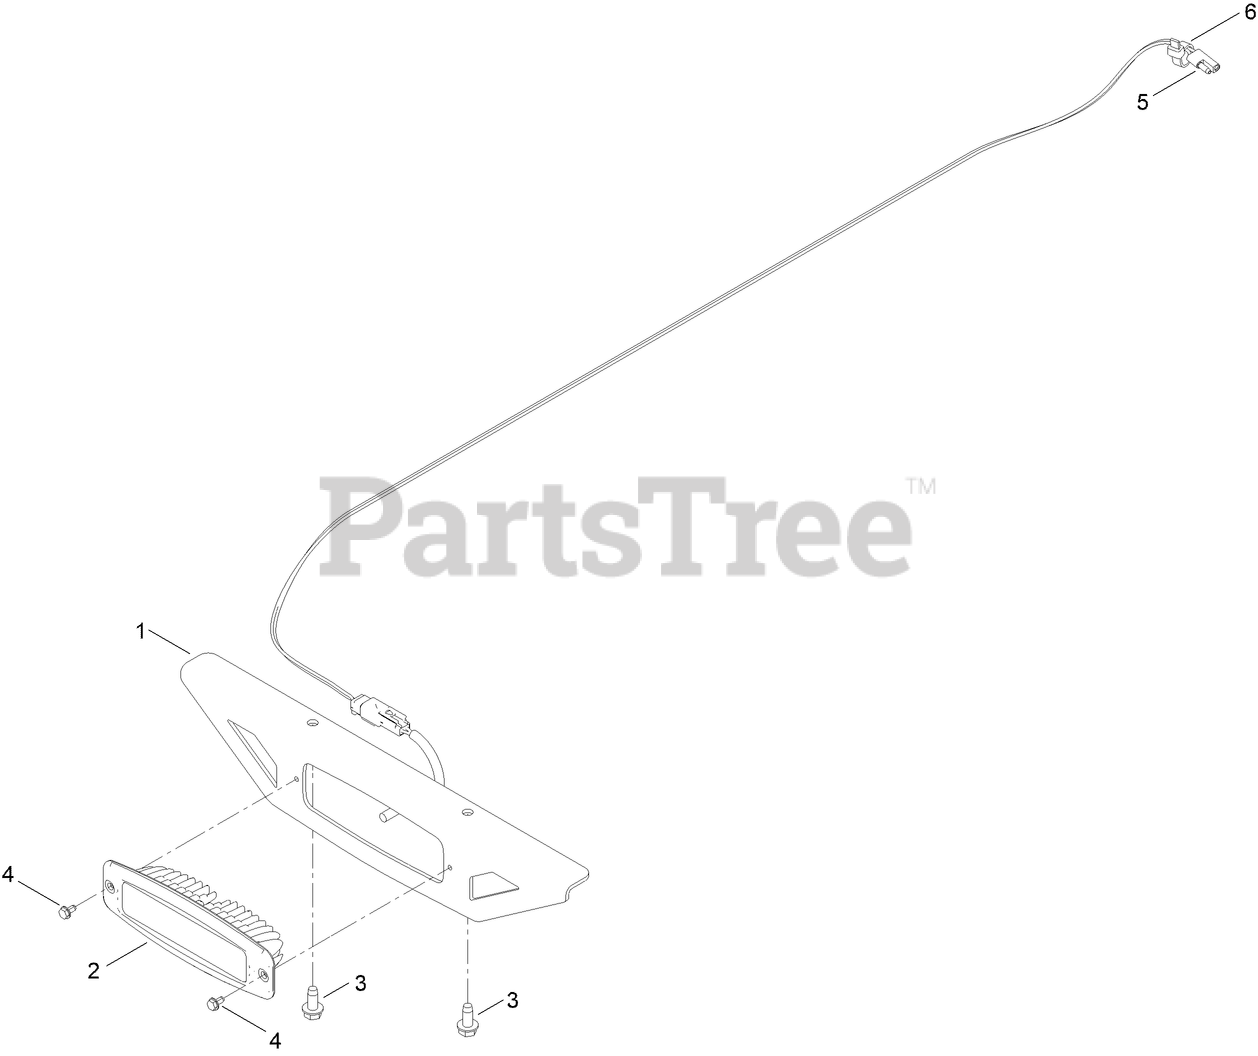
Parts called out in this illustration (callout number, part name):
1	BRACKET-LIGHT
2	MOUNT-FLUSH, LIGHT
3	SCREW-HWHTF
4	SCREW-HWH
5	HARNESS-WIRE. LED LIGHTS
6	TIE-CABLE
